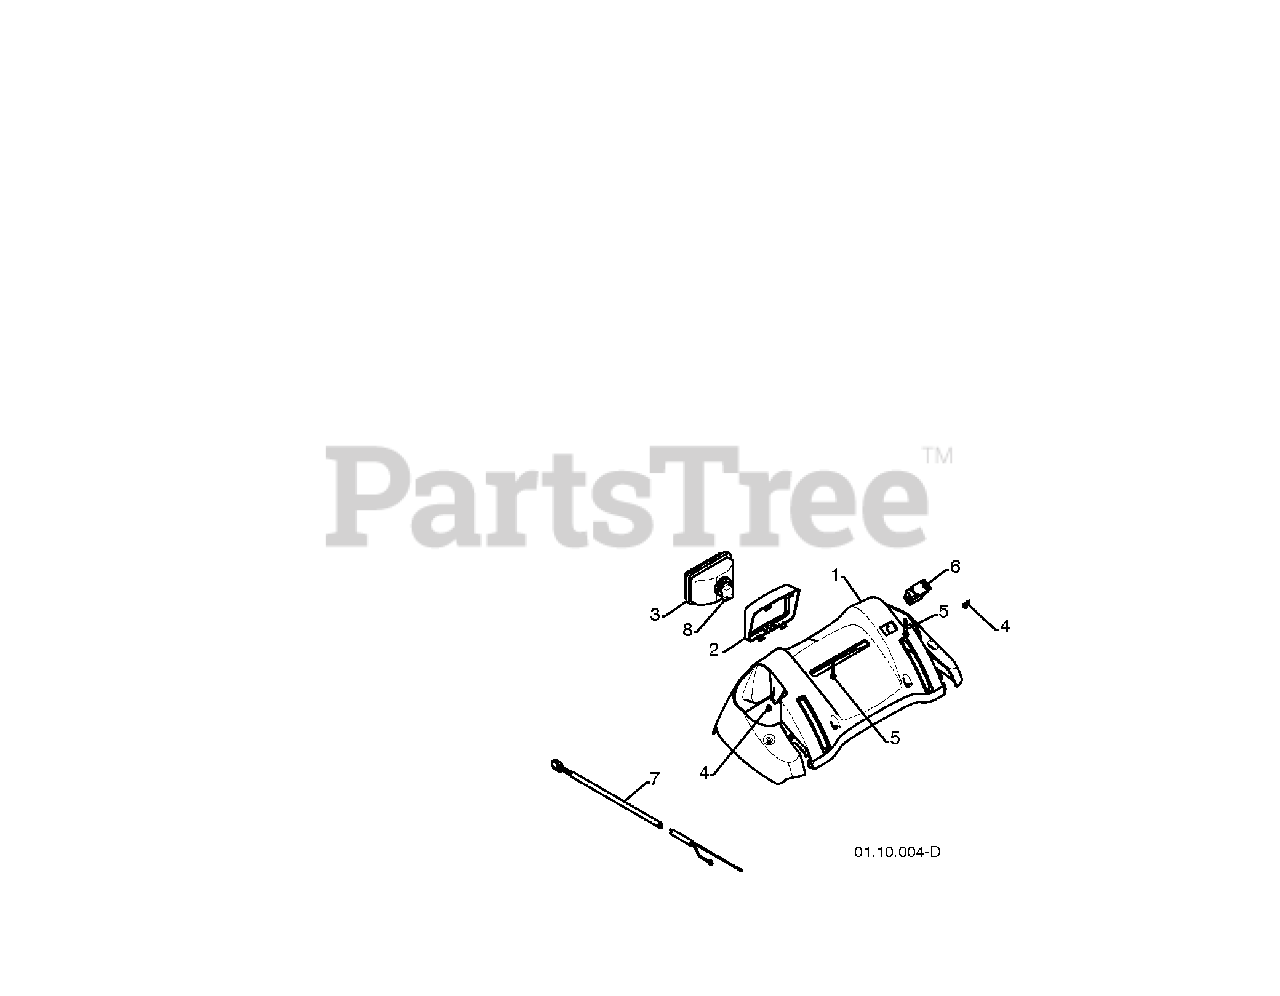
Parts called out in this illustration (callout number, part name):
2	BEZEL.HEADLIGHT.BLACK
3	HEADLIGHT, HALOGEN
4	SCREW, HEX HEAD, TAPPING
5	SCREW, HEX HD TAPPING #10-24 1
6	SWITCH.HEATED.GRIP
7	HARNESS.WIRE.LIGHT/GRIP.SNOW
8	BULB.HEADLIGHT.HALOGEN.
